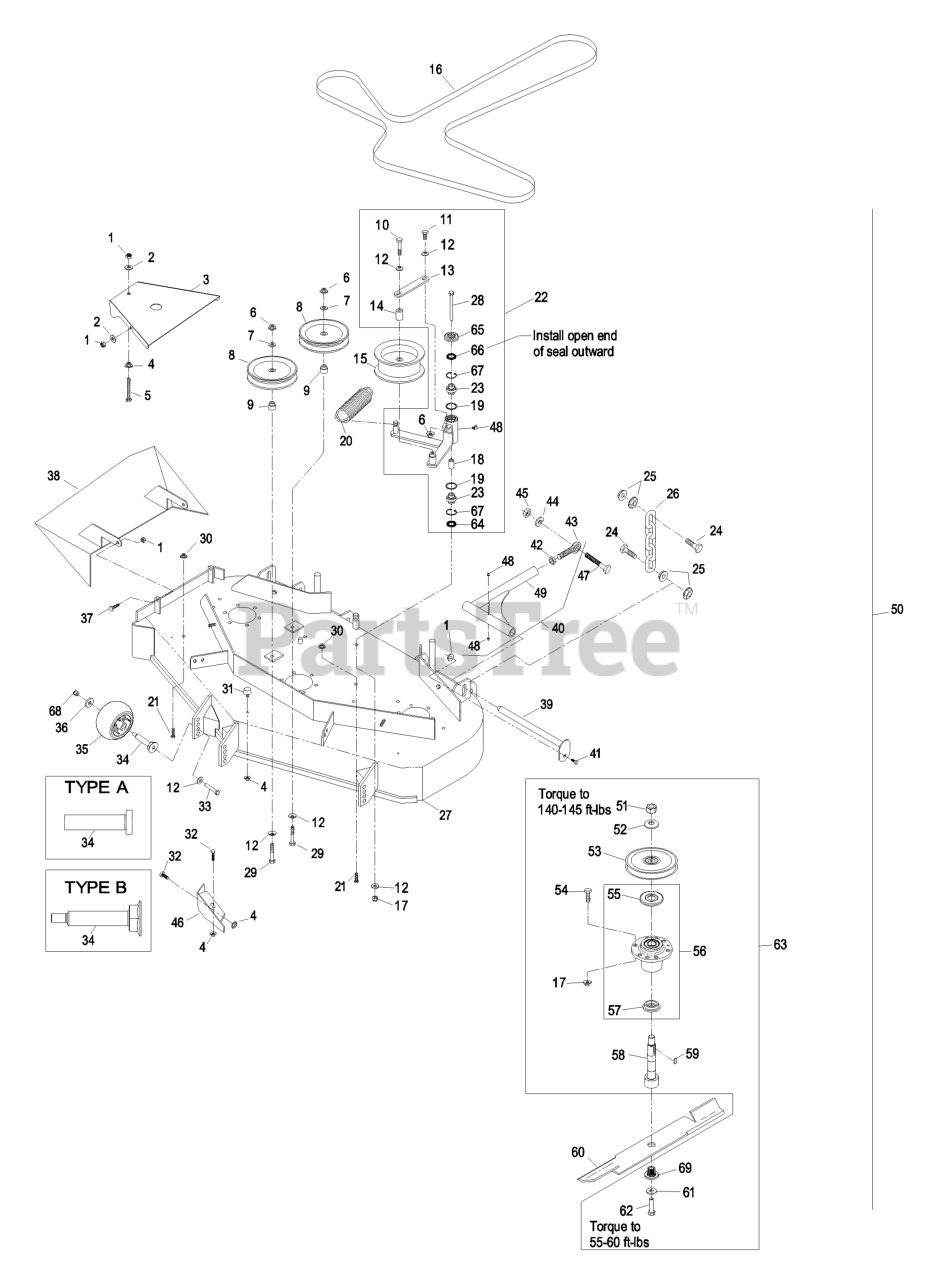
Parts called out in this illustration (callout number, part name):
1	NUT-LOCK, NI
2	WASHER-FLAT
3	SHIELD,BELT
5	BOLT,TAP HH
6	NUT-HHF, WHIZ
7	WASHER-FLAT
8	PULLEY-IDLER
9	BUSHING-IDLER
10	SCREW-HH
11	SCREW-HH
12	WASHER-BELLEVILLE
13	PLATE,GUIDE BELT (PLTD)
16	BELT,DECK DRIVE
17	NUT-LOCK, NI
21	SCREW-HH
22	KIT,DECK IDLER LHP/LCT
23	BEARING-SPHERICAL
24	SCREW-HH
26	CHAIN-LIFT, DECK
27	ASM,DECK W/DECALS LHP48 S
28	SCREW-HH
29	SCREW-HH
31	BUMPER-RUBBER
32	SCREW-HH
33	SCREW-HH
34	BUSHING-ROLLER
35	ROLLER-SCALP, ANTI
37	SCREW-HH
38	WLD,CHUTE 48
39	PIN-STRUT
40	STRUT ASM
41	SCREW-HH
42	NUT-HEX
43	BALLJOINT-SPHERICAL
44	WASHER-LOCK
45	NUT-HEX
48	FITTING-GREASE
50	Deck Complete Service (44")
51	NUT-HH
53	SHEAVE,W/HUB
54	SCREW-HH
55	GUARD-BEARING, TOP
56	KIT, CUTTER HOUSING
57	SPACER-GUARD, BOTTOM
58	KIT, SPLINED SPINDLE 103-
59	KEY-RECTANGLE
61	WASHER-SPRING
62	SCREW-HH
63	ASM, CUTTER HSG 44
64	SEAL-LIP, DOUBLE
65	GUARD-TOP
66	SEAL-LIP, SINGLE
67	RING-SNAP
68	NUT-HHF, WHIZ
69	BUSHING,SPLINED
